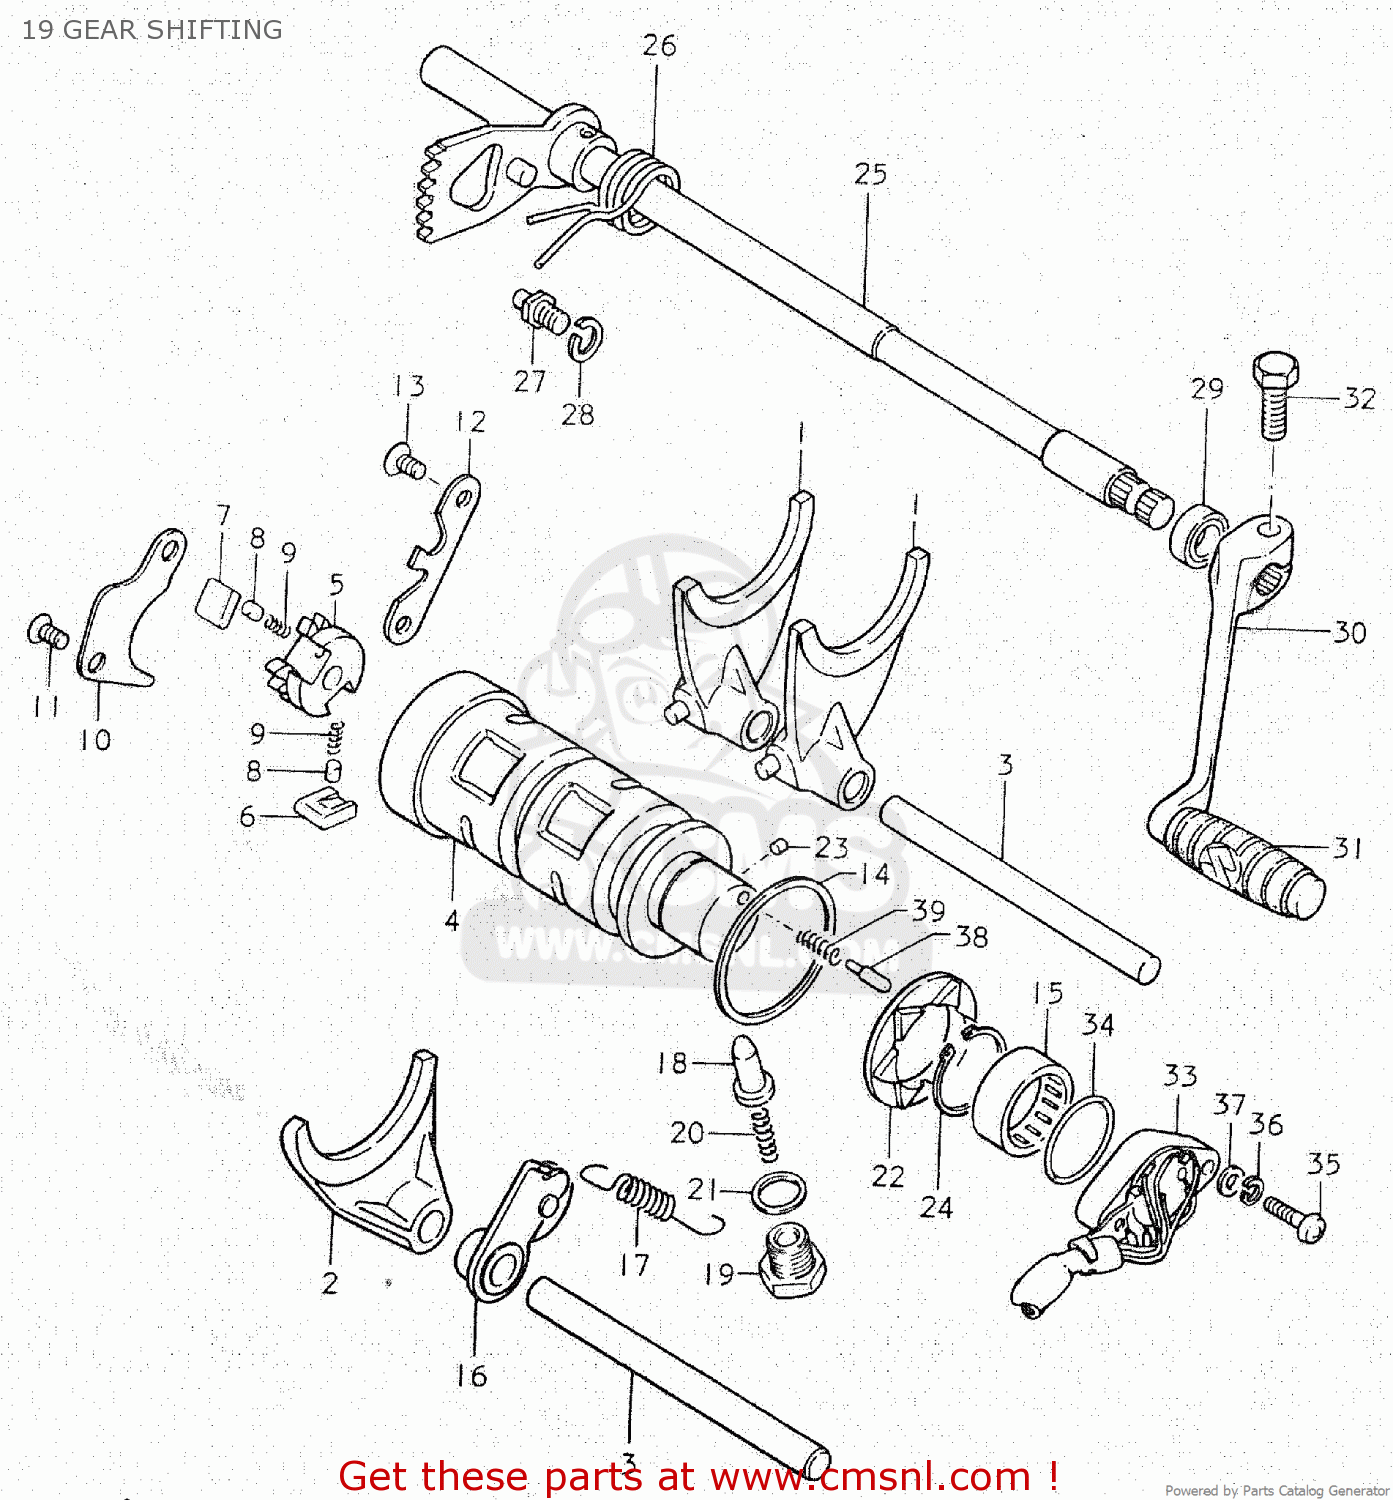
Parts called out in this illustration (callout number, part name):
1	FORK,GEAR SHIFT NO.1
2	FORK,GEAR SHIFT NO.3
3	SHAFT,GEAR SHIFT FORK
4	CAM,GEAR SHIFT
5	RETAINER,GEAR SHIFT CAM
6	PAWL,GEAR SHIFT NO.1
7	PAWL,GEAR SHIFT NO.2
8	PIN(5X8)
9	SPRING
10	LIFTER,GEAR SHIFT PAWL
11	SCREW
12	GUIDE,GEAR SHIFT CAM
13	SCREW
14	WASHER(40X45X1)
15	BEARING(25X32X12)
16	STOPPER,GEAR SHIFT CAM
17	SPRING
18	STOPPER,GEAR SHIFT CAM NO.2
19	HOLDER,GEAR SHIFT CAM STOP SPR
20	SPRING
21	GASKET(14X19.2X2) (NAS)
22	PLATE,GEAR SHIFT CAM STOPPER
23	PIN 4X6
24	CIRCLIP
25	SHAFT,GEAR SHIFT
26	SPRING
27	STOPPER,GEAR SHIFT CAM
28	LOCK WASHER
29	OIL SEAL
30	LEVER ASSEMBLY,GEAR SHIFTING
31	RUBBER,GEAR SHIFT PEDAL
32	BOLT
33	BASE ASSEMBLY,NEUTRAL SWITCH TERMINAL
34	O-RING (D:2.4 ID:26.2)
35	SCREW 5X20
36	LOCK WASHER
37	WASHER
38	PIN(5X15.5)
39	SPRING
